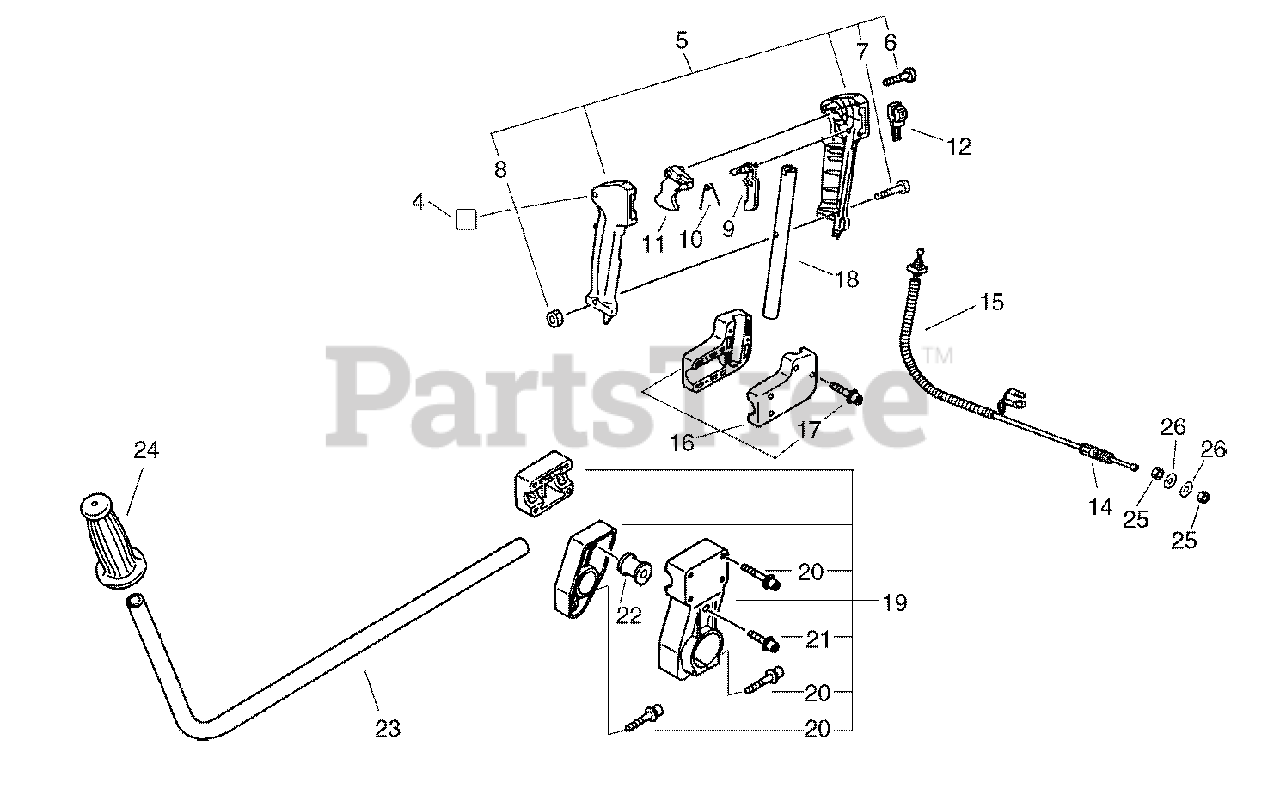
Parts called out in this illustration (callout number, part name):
4	LABEL - STOP
5	FRONT HANDLE GRIP ASSY
6	SCREW - 3X25
7	SCREW - 5X30
9	LOCKOUT, THROTTLE
10	SPRING, LOCKOUT LEVER
11	TRIGGER, THROTTLE
12	IGNITION SWITCH ASSY
14	CABLE, THROTTLE
15	TUBE
16	BRACKET, HANDLE
17	SCREW - 5X25
18	HANDLE - REAR
19	BRACKET, HANDLE
20	SCREW - 5X35
21	SCREW - 5X14
23	HANDLE - LEFT
23	HANDLE - FRONT
24	GRIP, HANDLE
26	WASHER - 6
